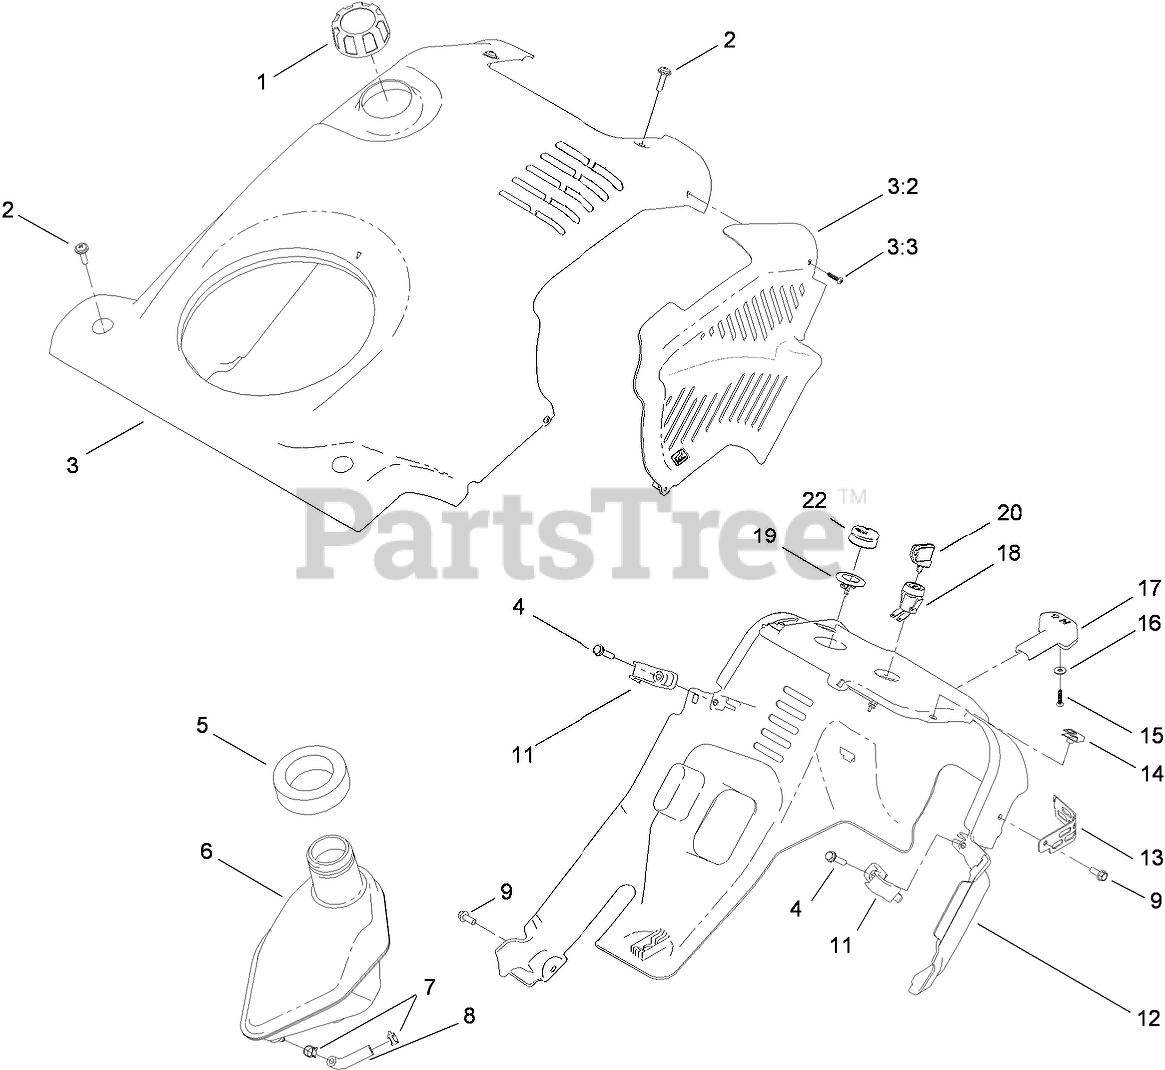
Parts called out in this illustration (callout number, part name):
1	4-CYCLE GAS CAP ASM
2	SCREW-PPH
3	SHROUD ASM
3:2	BAFFLE-HEAT, 4-CYCLE
3:3	SCREW-PPH
4	SCREW-PLASTITE
5	SEAL-TANK
6	TANK-GAS
7	CLAMP-HOSE
8	HOSE-FUEL
9	SCREW-HWH
11	CLIP-SHROUD
12	SHROUD-LOWER
13	GUARD-EXHAUST
15	SCREW-PPH
16	WASHER-PLAIN
17	KNOB-CHOKE
18	SWITCH
19	BODY-PRIMER
20	KEY-IGNITION
22	BULB-PRIMER
